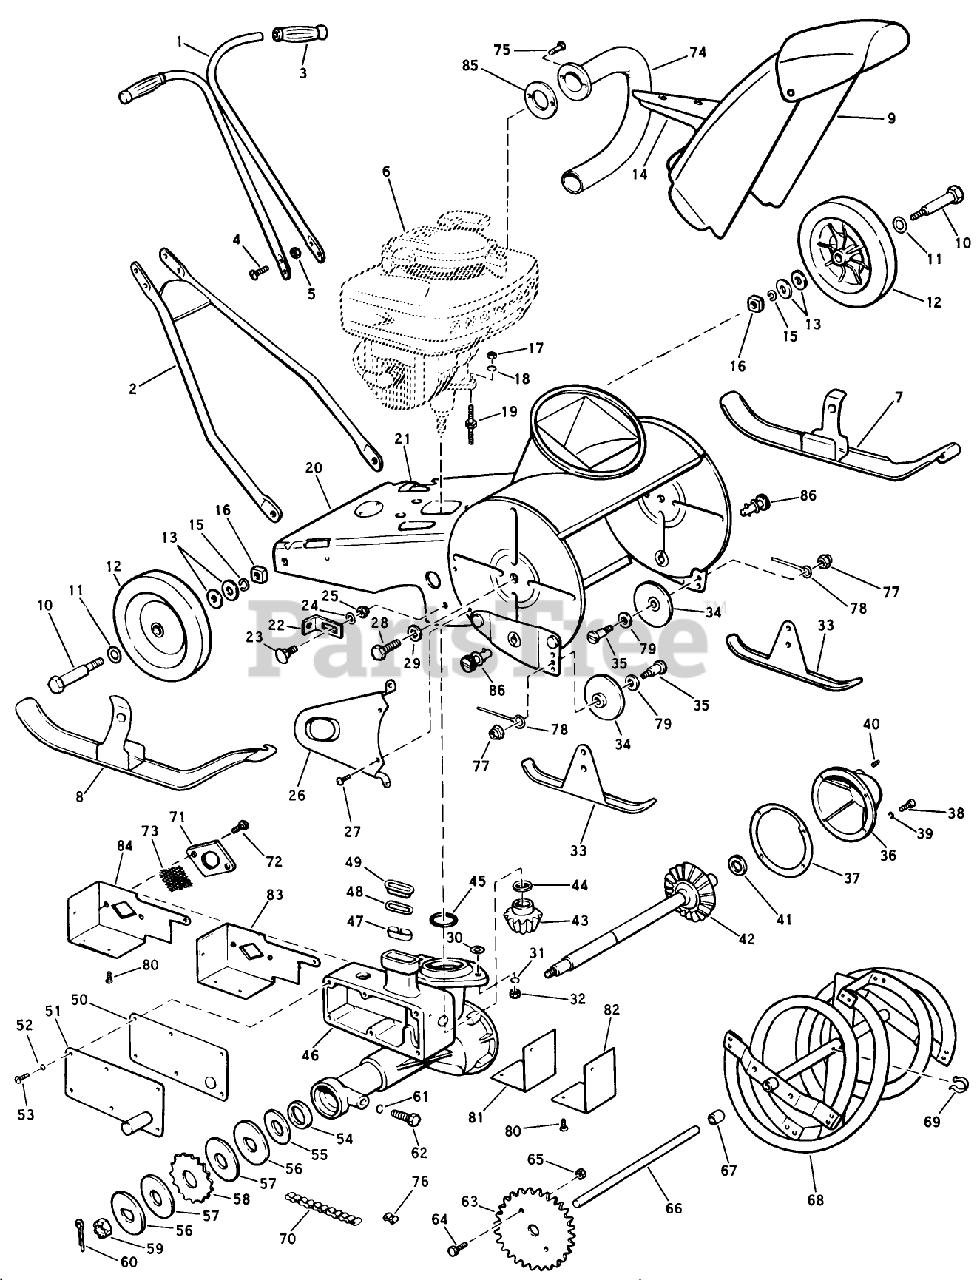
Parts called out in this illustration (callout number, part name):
2	Handle Assembly-Lower
5	STOP NUT
6	Engine Assembly
14	Positioning Pin
15	WASHER, LOCK
17	Nut-Engine Mounting
20	Base and Housing Assembly
25	Locknut-Sprocket Screw
30	Washer-Gearcase to Base Stud
32	Nut-Engine Mounting
36	Cover-Gearcase
38	Screw-Gearcase Cover
40	Plug-Oil Fill-Gearcase
41	Thrust Washer-Driveshaft Gear
42	Driveshaft and Gear Assembly
44	Thrust Washer-Pinion Gear
45	O Ring-G-case to Crankcase
46	Gearcase and Muffler
47	Liner-Muffler to Cylinder
51	Muffler Cover and Outlet Pipe
56	Washer-Steel "D" Hole
60	Cotter Pin-Driveshaft
65	Locknut-Sprocket Screw
